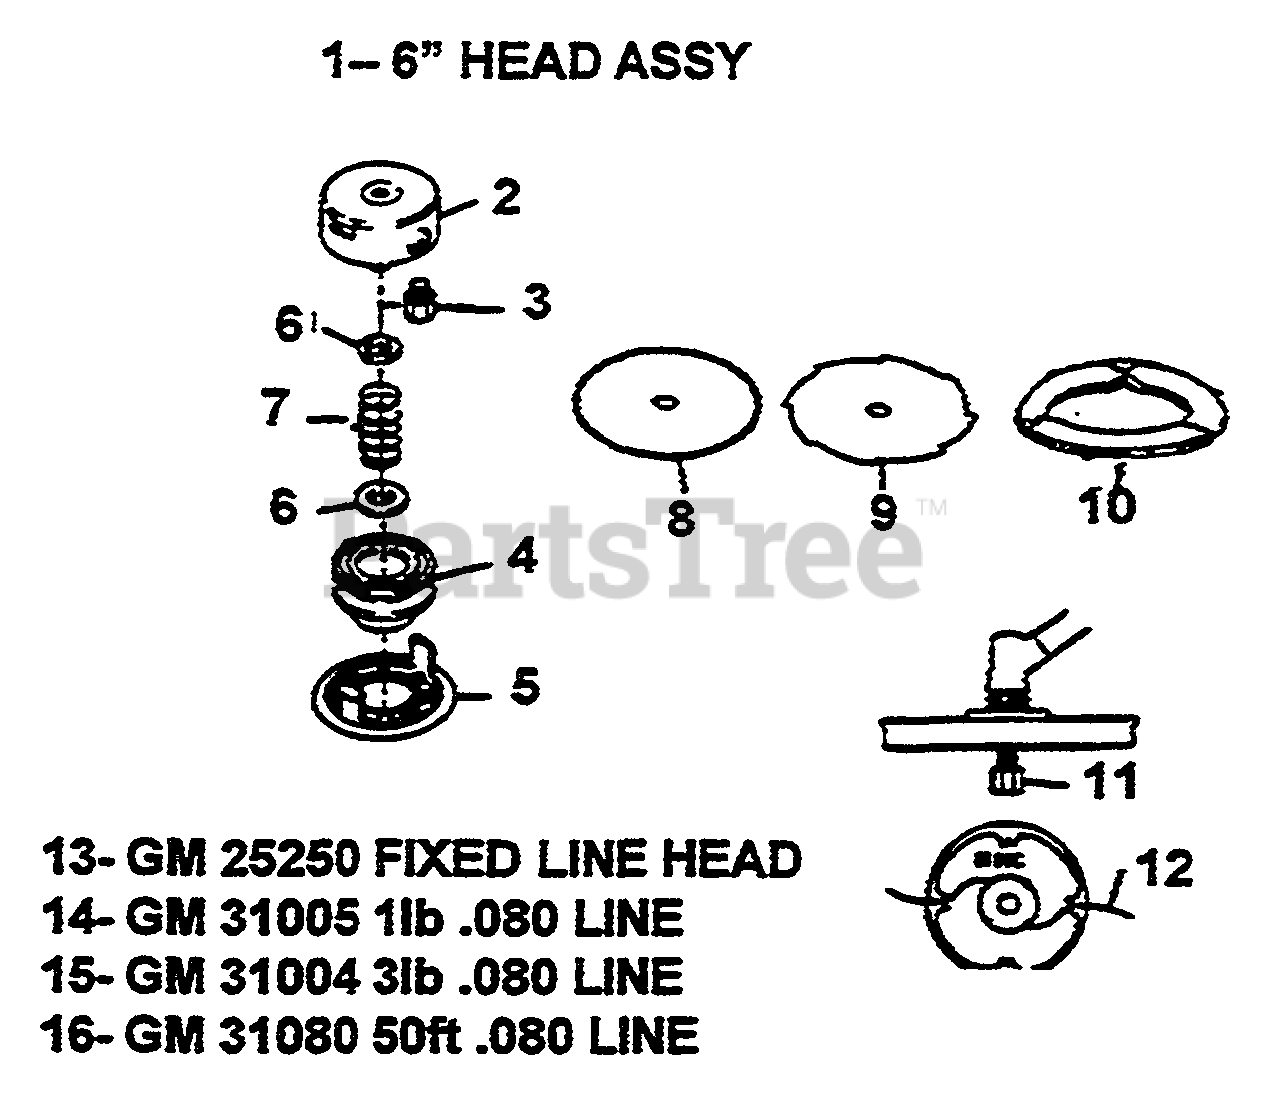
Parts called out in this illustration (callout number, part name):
1	6" HEAD ASSY
2	BODY
3	ARBOR BOLT
5	CAP
6	PLATE, SPRING
7	SPRING
8	9" SAW BLADE
9	9" BRUSH BLADE
10	BLADE COVER
11	ARBOR BOLT
12	.105 LINE, 20" STRIPS
13	FIXED LINE HEAD
14	1lb .080 LINE
15	3lb .080 LINE
16	50ft .080 LINE
